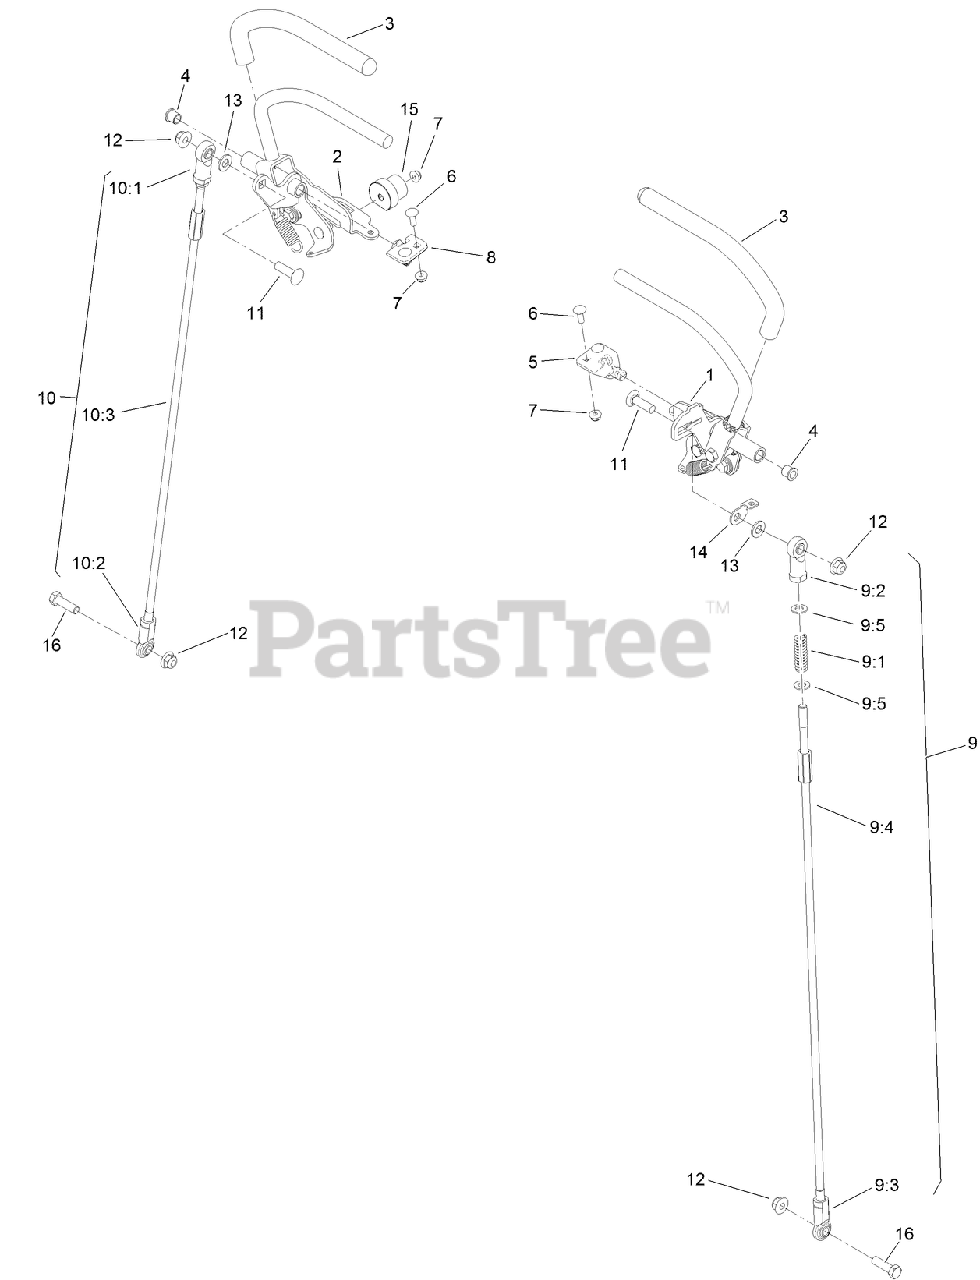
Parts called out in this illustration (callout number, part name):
1	LH CONTROL HANDLE ASM
2	RH CONTROL HANDLE ASM
4	BEARING
5	TAB-PIVOT, LH
6	BOLT-CARR
7	NUT-HF
8	TAB-PIVOT, RH
9	LH CONTROL ROD ASM
9:1	SPRING-RETURN, NEUTRAL
9:2	END-ROD, FEMALE
9:3	JOINT-BALL END, LH
9:4	ROD-CONTROL
9:5	WASHER-FLAT
10	RH CONTROL ROD ASM
10:1	END-ROD, FEMALE
10:2	JOINT-BALL END, LH
10:3	ROD-CONTROL
11	SCREW-CARR
12	NUT-HF, NI
13	WASHER-FLAT
14	BRACKET-ADJUSTMENT, SPEED
16	SCREW-HH
